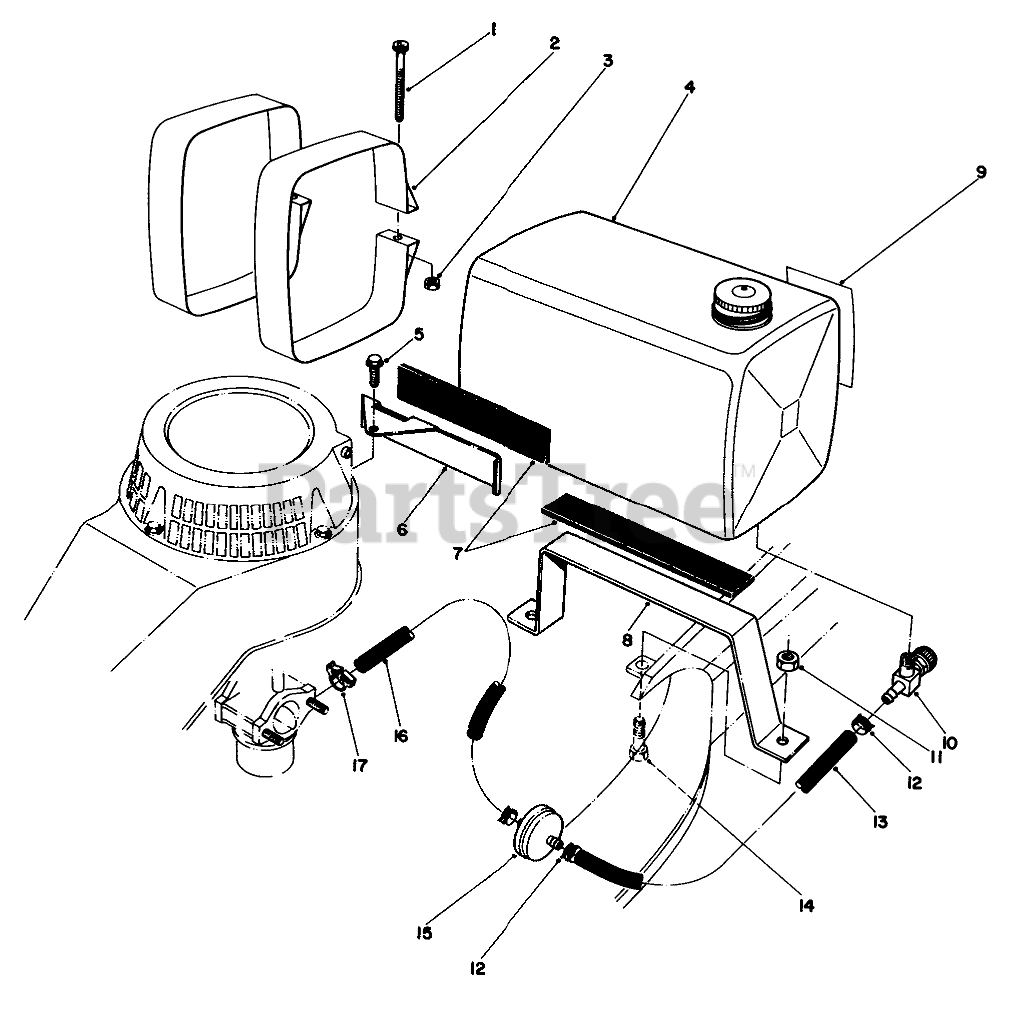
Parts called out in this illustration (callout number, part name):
1	SCREW-HSH
2	TANK MTG STRAP WA
3	NUT-HEX
4	Tank-Gas
5	SCREW-HHF
6	FRT TANK MOUNT
7	ISOLATOR PAD
8	BOTTOM TANK MOUNT
9	FUEL TANK DECAL
10	.125 ID SHUTOFF VALVE
11	NUT-LOCK, CONE
12	FUEL HOSE CLAMP
13	HOSE-FUEL
14	SCREW-HH
15	Filter-Fuel
16	LINE-GAS
17	FUEL LINE CLAMP
